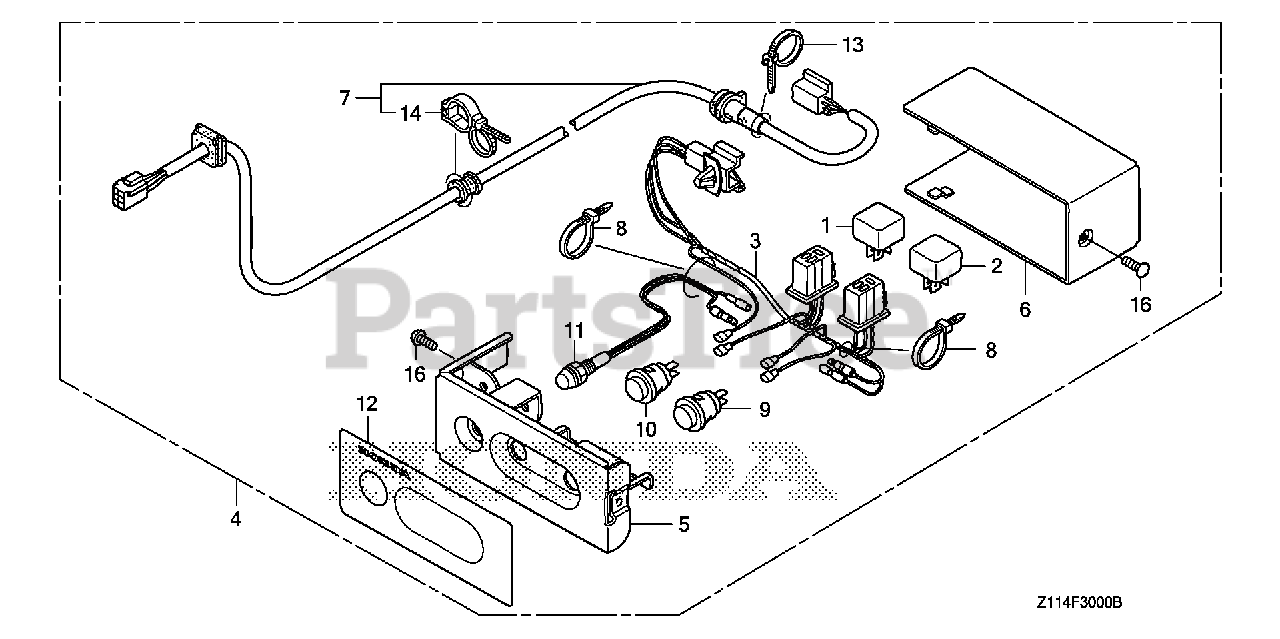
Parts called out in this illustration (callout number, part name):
1	RECTIFIER, SILICON
2	RECTIFIER, SILICON
3	HARNESS ASSY., REMOTE CONTROL
4	BOX ASSY., REMOTE CONTROL (10M) *NH105* (MAT BLACK)
4	BOX ASSY., REMOTE CONTROL (20M) *NH105* (MAT BLACK)
4	BOX ASSY., REMOTE CONTROL (30M) *NH105* (MAT BLACK)
5	PANEL, REMOTE CONTROL *NH105* (MAT BLACK)
6	COVER, REMOTE CONTROL *NH105* (MAT BLACK)
7	CABLE ASSY., REMOTE CONTROL (10M)
7	CABLE ASSY., REMOTE CONTROL (20M)
7	CABLE ASSY., REMOTE CONTROL (30M)
8	TIE, CABLE (C)
9	SWITCH, ENGINE STOP
10	SWITCH, START
11	LED ASSY.
12	MARK, REMOTE CONTROL
13	BAND, HARNESS (98MM) (NATURAL)
14	CLIP, TUBE (135MM) (BLACK)
16	SCREW, PAN (4X8)
